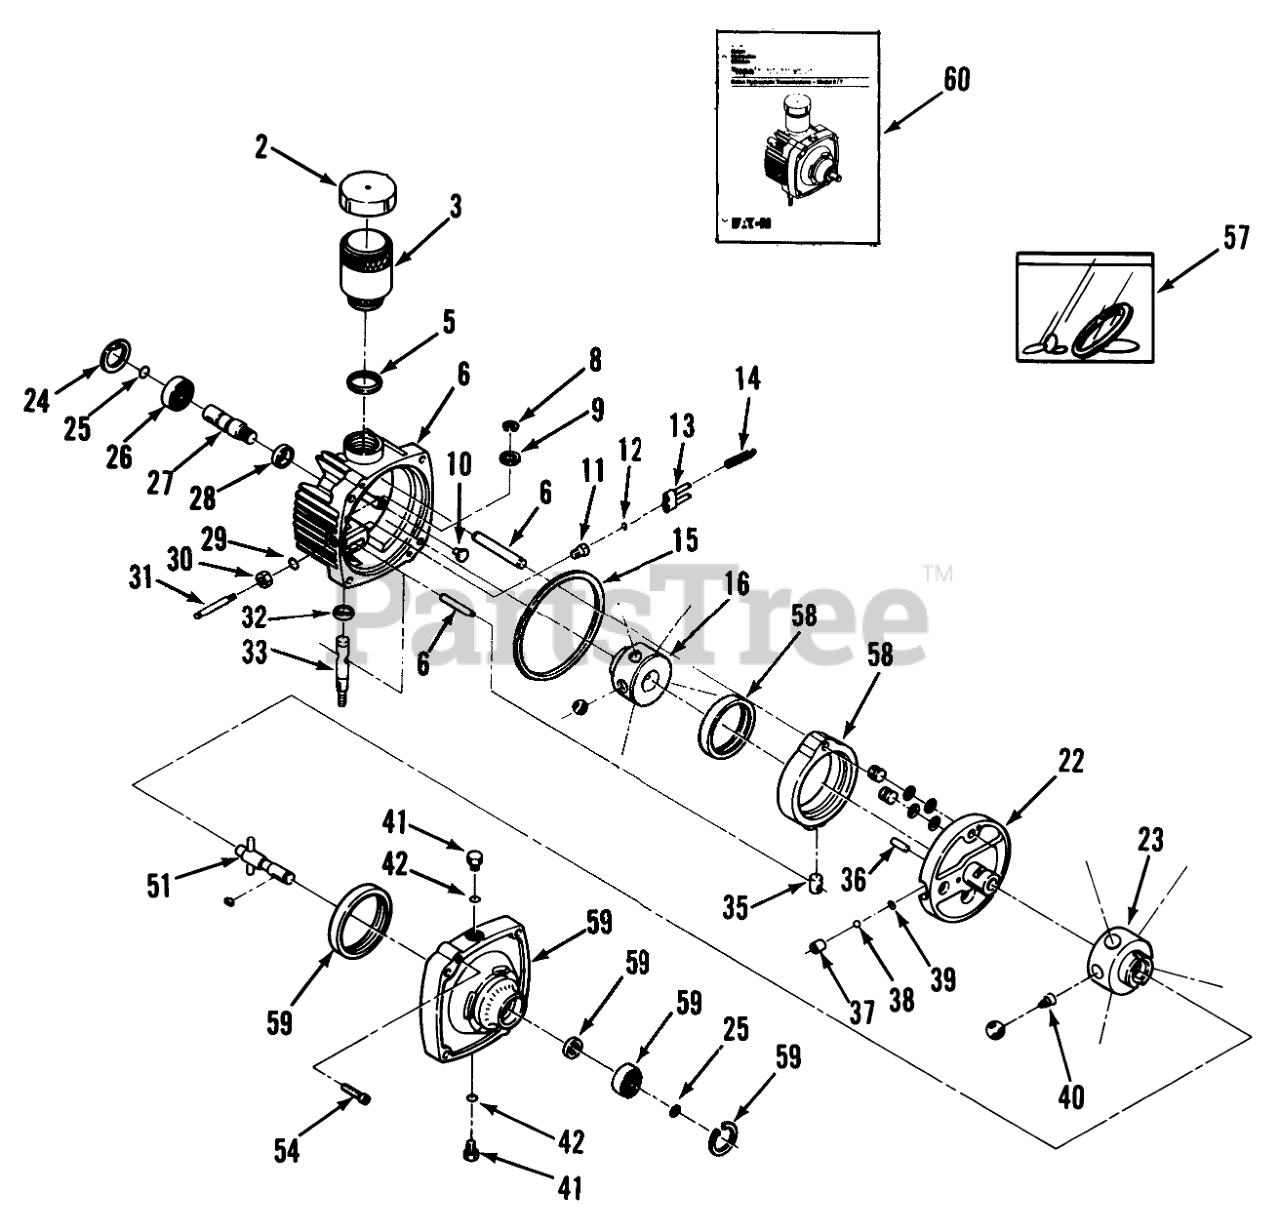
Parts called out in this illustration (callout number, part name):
2	RESERVOIR COVER
3	BODY-RESERVOIR
5	Square Cut Seal Ring (Included in item 57)
6	Cover Service Kit (Includes Pivot Pin Dowel, Control Shaft Dowel, & Items 8, 9, 28, 32 & 33)
8	Extemal Retaining Ring (Included in item 6)
9	Washer-Control Shaft
10	Button
11	"O" Ring Fitting Guide Sub-assembly (Includes item 12)
12	Dump Valve Bracket "O" Ring (Included in item 11 & 57)
13	SUB-ASS'Y BRACKET
14	SPRING-VALVE
15	Square Cut Seal Ring (Included in item 57)
16	SUB-ASS'Y PUMP ROTOR
22	Pintle Sub-assembly-Used in CCW rotation trans. Model No. 00700-023 (Includes Piston, Backup Ring, "O" Ring, & Items 36, 37, 38 & 39)
23	SUB-ASS'Y MOTOR
24	Retaining Ring
25	SNAP-RING
26	BEARING-BALL (INPUT)
27	SHAFT-INPUT
28	Oil Seal (Included in item 6 & 57)
29	Dump Valve "O" Ring (Included in item 57)
30	Nut-Gasket Sub-assembly (Included in item 57)
31	PULLEY FLAT B
32	Oil Seal (Included in item 6 & 57)
33	Control Shaft Kit (Included in item 6)
35	INSERT-CAM RING
36	Coil Pin (Included in item 22)
37	Check Valve Body (Included in item 22)
38	Grade 200 Ball 5/16 O.D. (Included in item 22)
39	Retaining Ring (Included in item 22)
40	Piston Spring (Included in item 23)
41	"O" Ring Plug Sub-assembly (Includes item 42)
42	Tube Fitting "O" Ring (Included in item 41 & 57)
51	Output Shaft Sub-assembly (Included in item 59)
54	Screw
57	Overhaul Sealing Kit (Includes Dampening Piston "O" Rings, Dampening Piston Backup Rings, Output Shaft Oil Seal, Plug "O" Ring & items 5, 11 w/12, 15, 28, 29, 30, 32 & 42)
58	Cam Ring Sub-assembly (Includes Pump Race & Cam Riing)
59	Body Sub-assembly (Includes Body, Oil Seal, Output Ball Bearing, Snap Ring, Retaining Ring, Motor Race & Item 51)
60	Hydrostatic Transmission Repair Manual
